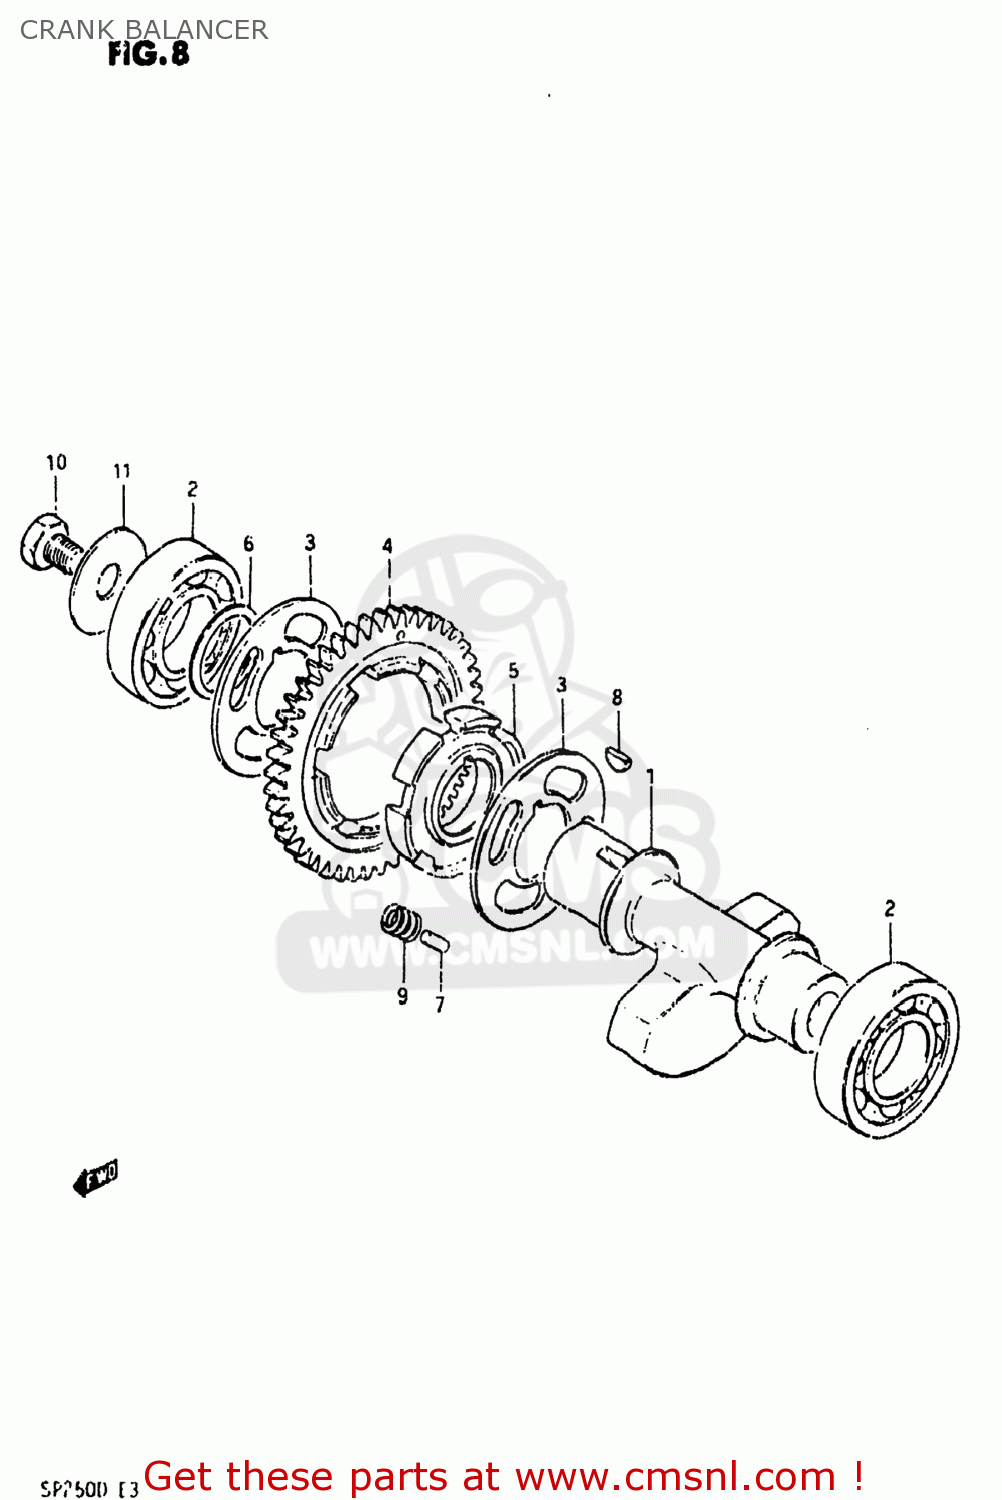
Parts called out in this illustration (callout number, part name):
1	BALANCER,CRANKSHAFT
2	BEARING
3	WASHER
4	GEAR,CRANK BAL DRIVEN(NT:46)
5	RACE,CRK BAL DRIVEN GR INNER
6	SHIM
7	PIN
8	KEY 4MM
9	SPRING
10	BOLT ,12X16
11	WASHER
